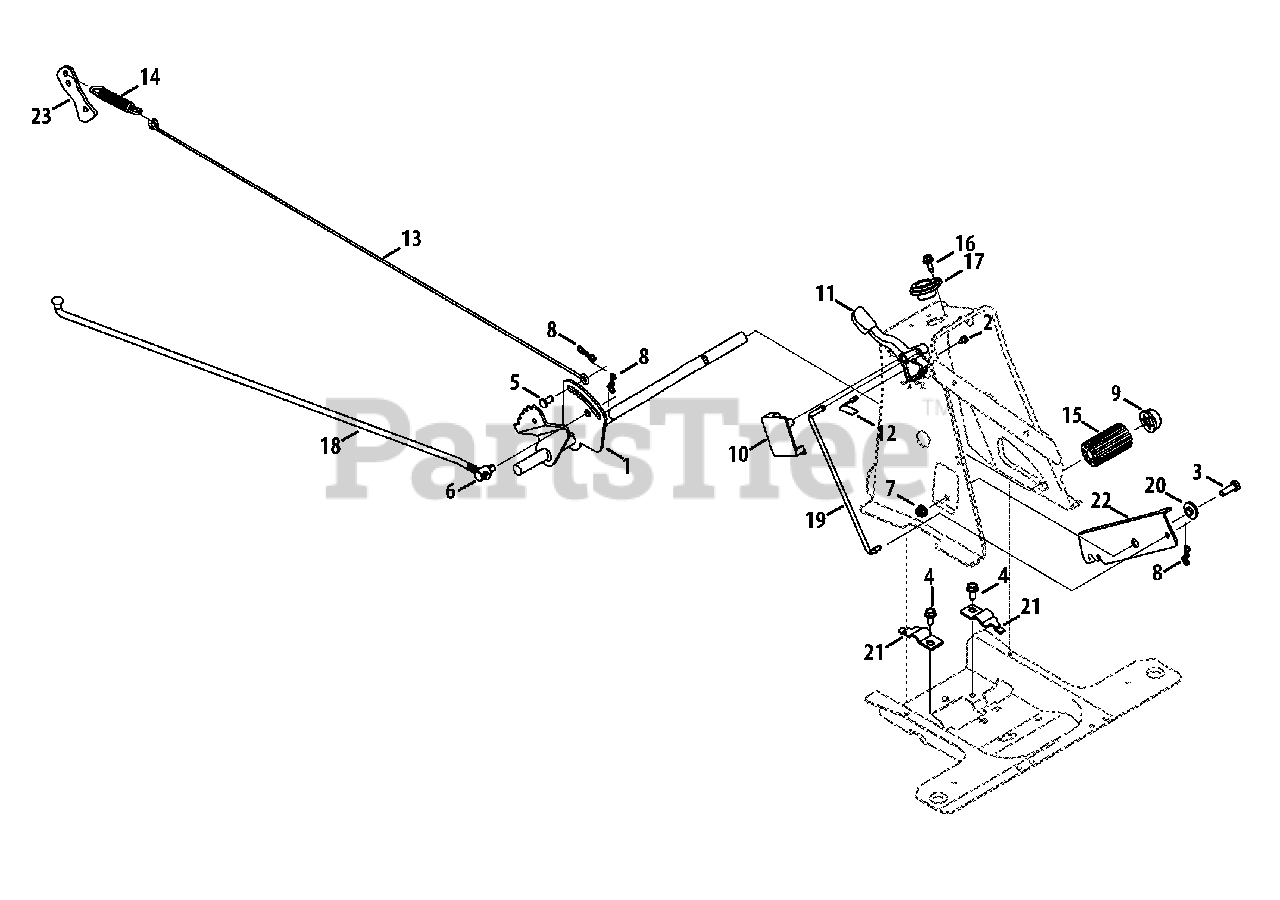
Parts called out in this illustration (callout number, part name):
1	Brake Pedal Assembly
2	Screw, #10-16:0.500
3	Hex Head Scerw, 5/16-18:1.00
4	Tap Screw, 5/16-18:.750
5	Clevis Pin, 5/16 x 5/8
6	Ferrule 3/8-24 X .375 Dia.
7	Flange Lock Nut, 5/16-18
8	Bow-Tie Cotter Pin, 72
9	Push Cap, 5/8
10	Speed Control Cover
11	Speed Lever, 6-SPEED
12	Shift Spring
13	Brake Rod, 39.92 LG
14	Extension Spring, .59 OD x 4.00 LG
15	Foot Pad, 2.5" LG.
16	Shoulder Screw, .368 X.113, 1/4-20
17	Steering Col. Bearing, .880 ID X 1.36
18	Variable Speed Control Rod
19	Speed Selector Control Rod
20	Shoulder Spacer
21	Pedal Strap Support Bracket, 5/8
22	Speed Latch Bracket
23	Brake lever Bracket
